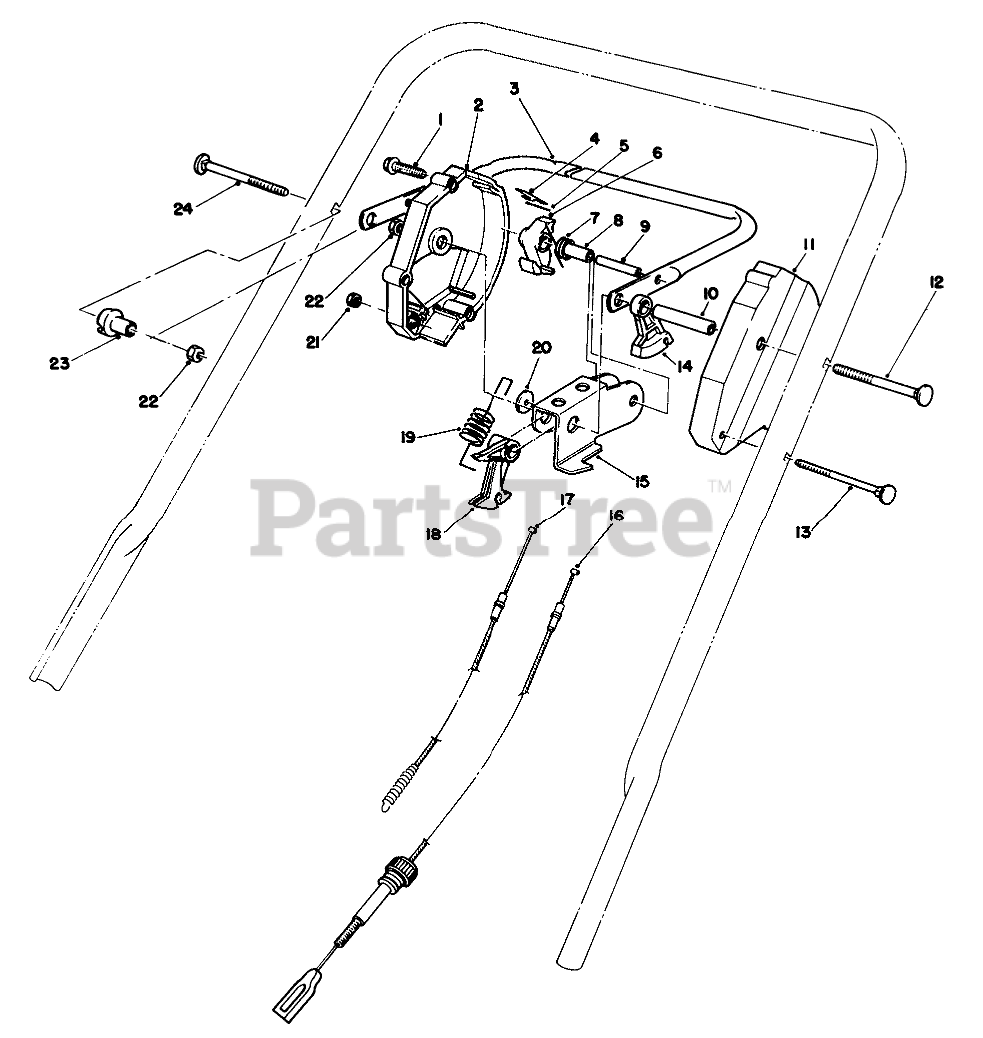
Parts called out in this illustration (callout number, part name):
1	SCREW-HWHTF
2	Housing-Control R.H. (Incl. Ref. #4 & 5)
3	Bar-Control
4	SPRING-LEAF
5	PIN-INSERT
6	HOOK-CONTROL
7	SPRING-TORSION
8	SPACER
9	PIN-ROLL, SLOTTED
10	TUBING-SPACER
11	HOUSING-CONTROL, LH
12	5/16-18 X 3 HNDLE SCREW
13	HANDLE SCREW
14	LEVER-TRACTION
15	ROCKER
16	TRACTION CABLE
17	Cable-Clutch
18	LEVER-CABLE
19	SPRING-DETENT
20	WASHER-NYLON
21	NUT-HEX
22	NUT-LOCK, NI
23	SPACER-SUPPORT
24	5/16-18 X 2 HNDLE SCREW
